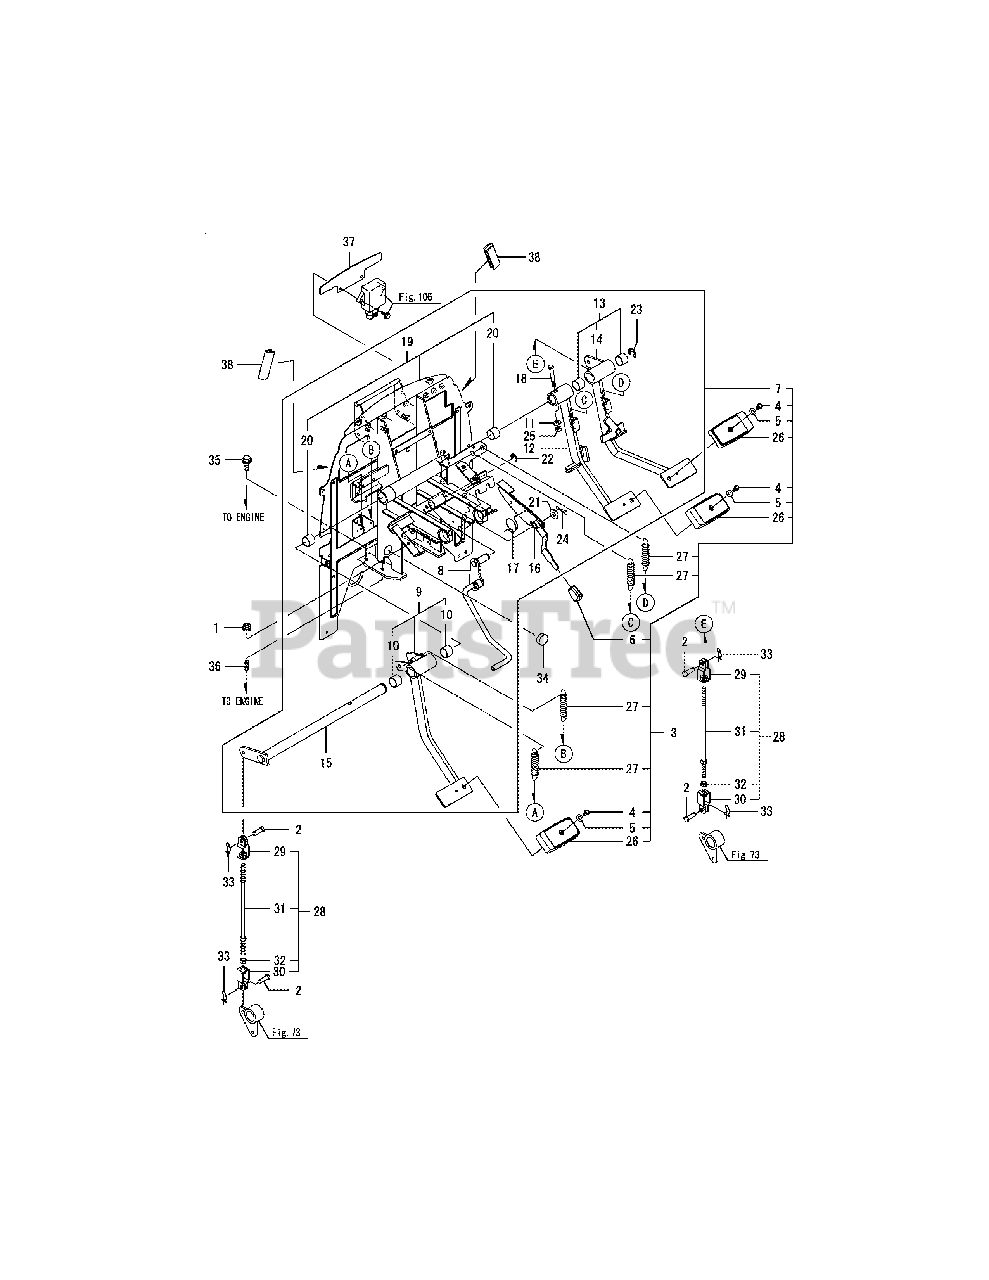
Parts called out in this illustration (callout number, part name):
1	NUT W/WASHER 8
4	RIVET,PEDAL HEAD
7	PEDAL SUB UNIT
8	PEDAL ASSY, TILT
9	PEDAL ASSY, CLUTCH
11	WASHER 8.5X20X3.2
12	PEDAL ASSY, BRAKE L
13	PEDAL ASSY, BRAKE R
14	PEDAL ASSY, BRAKE R
16	LEVER, PARK LOCK
18	REAMER BOLT M 8X55
19	FRAME ASSY, PEDAL
21	WASHER 12,POLISHED
24	COTTER PIN 2.5X30
26	COVER,PEDAL HEAD
28	ROD KIT, BRAKE F
29	JOINT,L SCREW FORK
31	ROD ASSY, BRAKE
33	PIN 8,COME-OFF SNAP
34	HOLE PLUG, 27.8
35	BOLT M 8X 16 PLATED
36	STUD BOLT M8X16
37	SUPPORT, DASHBOARD
38	COVER,HOSE PROTECTOR
